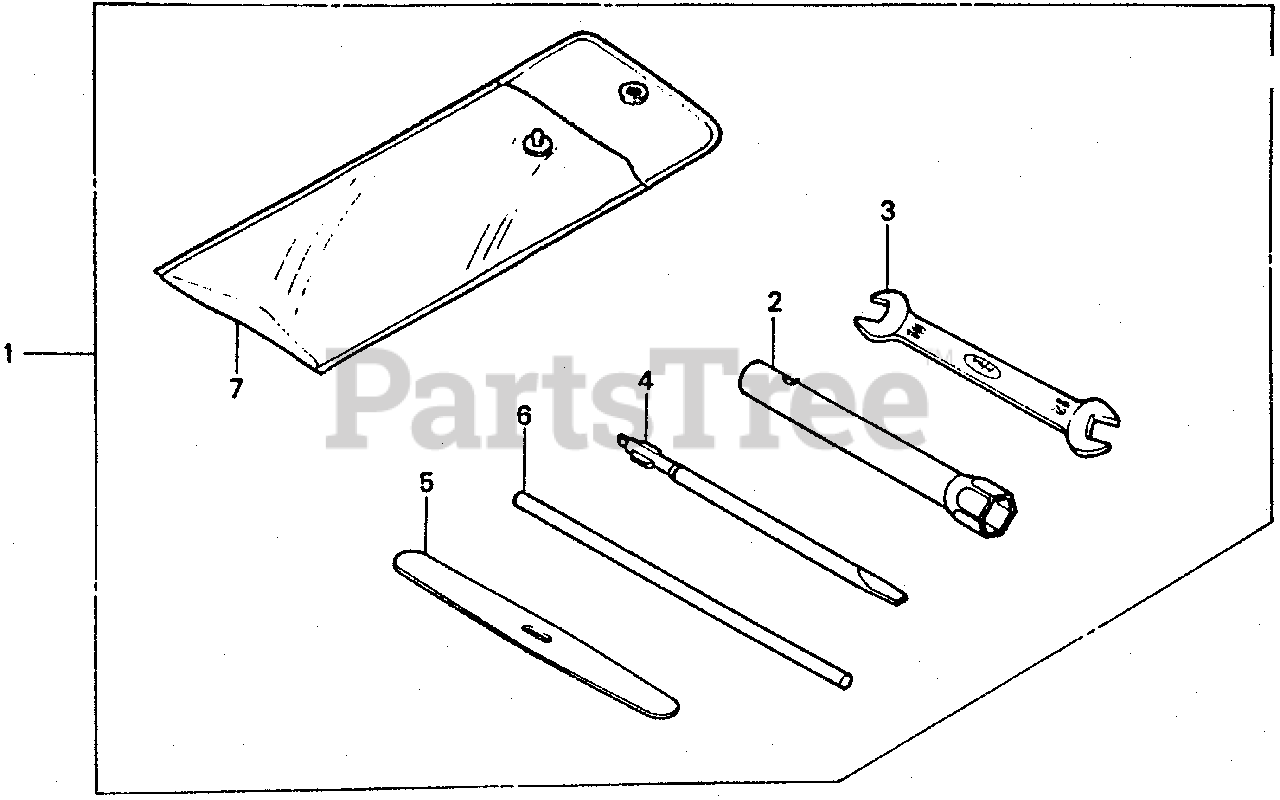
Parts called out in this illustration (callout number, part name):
2	WRENCH, PLUG
3	WRENCH (10X12) (OPEN END)
4	SCREWDRIVER 3, STRAIGHT SLOT (NO.2)
5	LEVER, TIRE
6	BAR A, HANDLE
